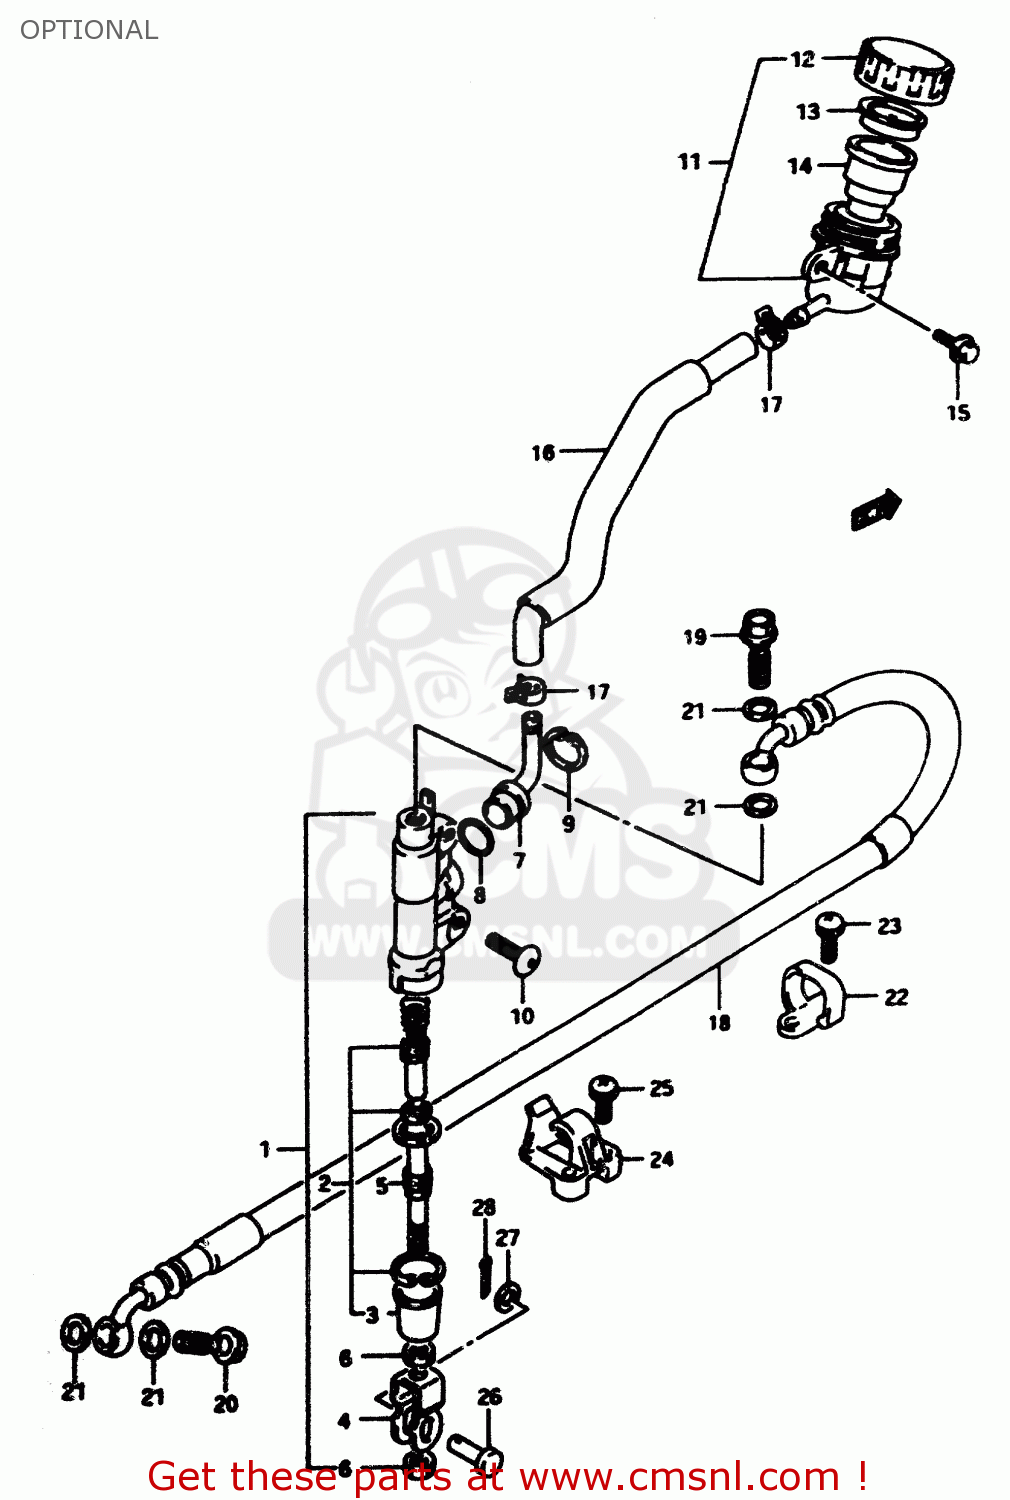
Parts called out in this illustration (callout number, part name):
1	THREAD LOCK SUPER(1360)
2	THREAD LOCK NO.1401 CLEAR 200G
3	LIQUID GSKT NO.1215 250G
4	GREASE(C)EP2 LITHIUM 150G
5	SUZUKI MOLY PASTE
6	GREASE,PBC FOR BRK PAD 20G
